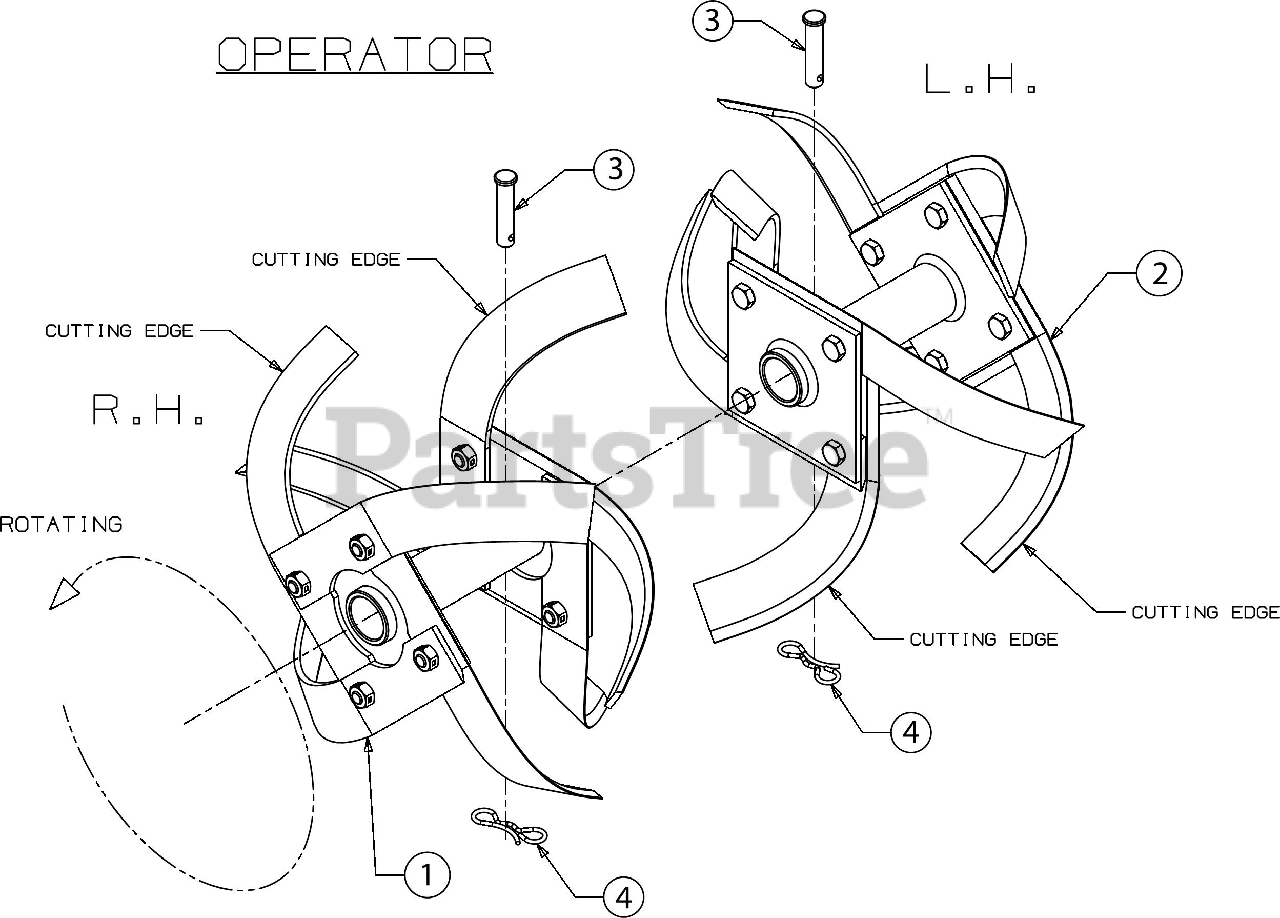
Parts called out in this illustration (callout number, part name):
1	HEX NUT
1	SCREW 5/16-18 x .75 GR5
2	HEX NUT
2	SCREW 5/16-18 x .75 GR5
3	CLEVIS PIN .375 x .1.75
4	PIN:COTTER
